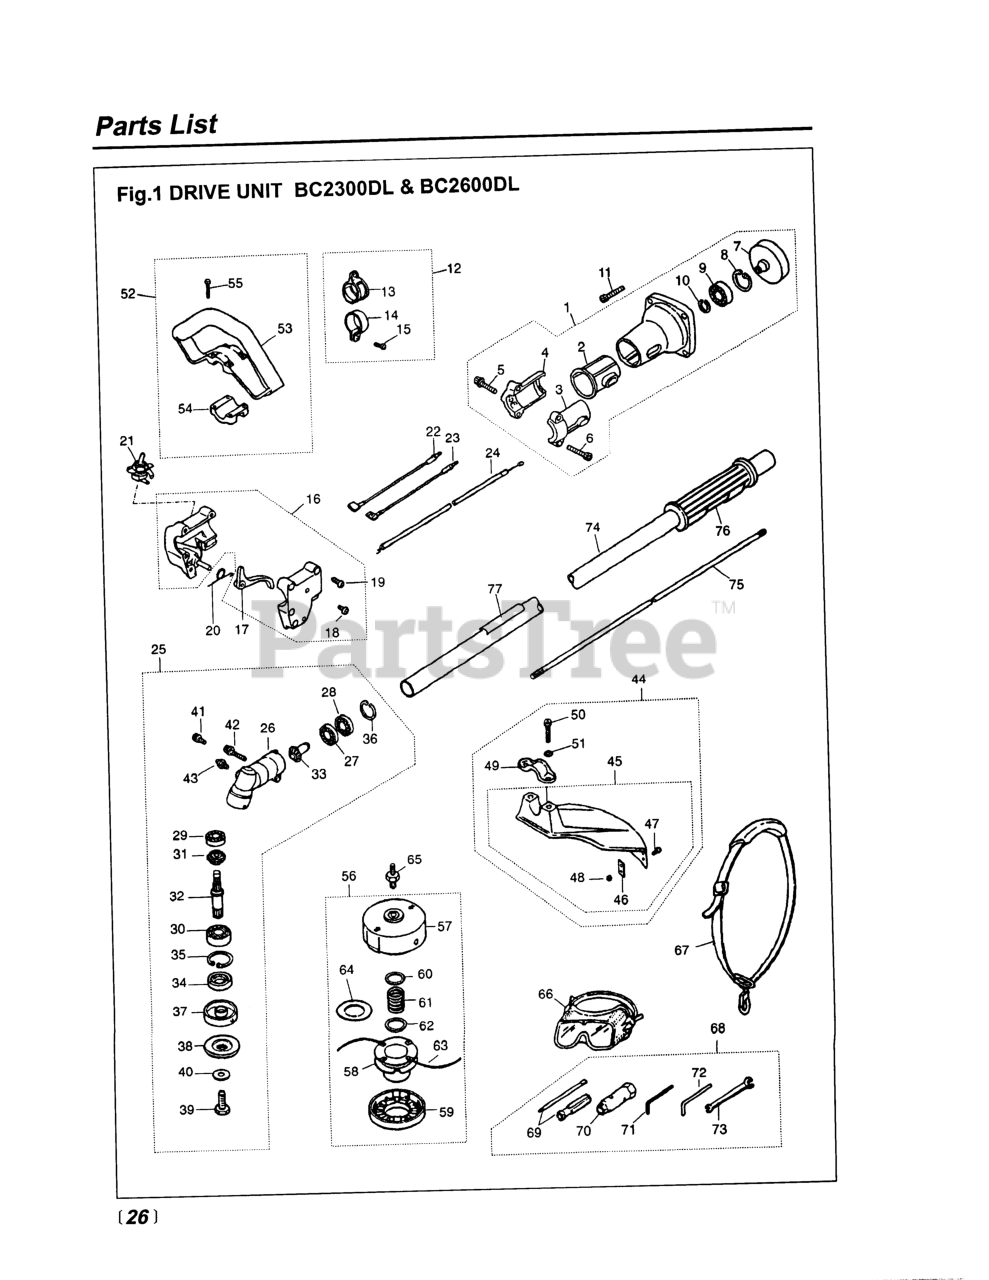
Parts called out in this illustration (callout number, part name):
2	CUSHION
3	BRACKET (USE -31211)
4	BRACKET (USE -31221)
5	BOLT (USE 3310-31720)
6	BOLT, M5 X 30
8	RING, SNAP, M28 x 1.2
9	BEARING
10	RING, SNAP (RPLS 3130-13270)
11	BOLT, M6 x 20
12	HANGER COMPLETE
13	HANGER
14	CLAMP
15	SCREW, M5 x 25
17	THROTTLE HSG & TRIGGER
18	SET SCREW, ANTI-ROTATION
19	SCREW
20	SPRING, THROTTLE TRIGGER
21	SWITCH, STOP
22	CORD, RED (LEAD WIRE)
23	CORD, BLACK (LEAD WIRE)
24	CABLE COMP (RPLS 6460- )
25	GEARCASE ASSEMBLY
26	GEARCASE
27	BEARING
28	BEARING
29	BEARING
30	BEARING
31	GEAR
33	PINION
34	SEAL, OIL
35	RING, SNAP
36	RING, SNAP
37	HOLDER (A)
38	HOLDER (B)
40	WASHER
41	BOLT, M5 x 12
42	BOLT, M5 X 25
43	FITTING, GREASE
44	GUARD ASSEMBLY
46	BLADE
47	SCREW, M5 x 12
48	NUT
49	CLAMP
50	BOLT, M6 x 1.30
51	WASHER, M6 X 15
52	HANDLE ASSEMBLY
53	HANDLE
54	CLAMP
55	SCREW, M5 x 35
56	4
59	COVER (RPLS -15130)
60	PLATE, LARGE
62	PLATE, SMALL
63	CORD
64	SPACER
65	ARBOR, 8MM
66	GOGGLE
67	SHOULDER STRAP ASSY
68	TOOL SET
69	SCREWDRIVER
71	WRENCH (TOOL)
72	BAR
73	SPANNER, 8 X 10 (RPLS 2540- )
77	LABEL, BC2300/2600DL
